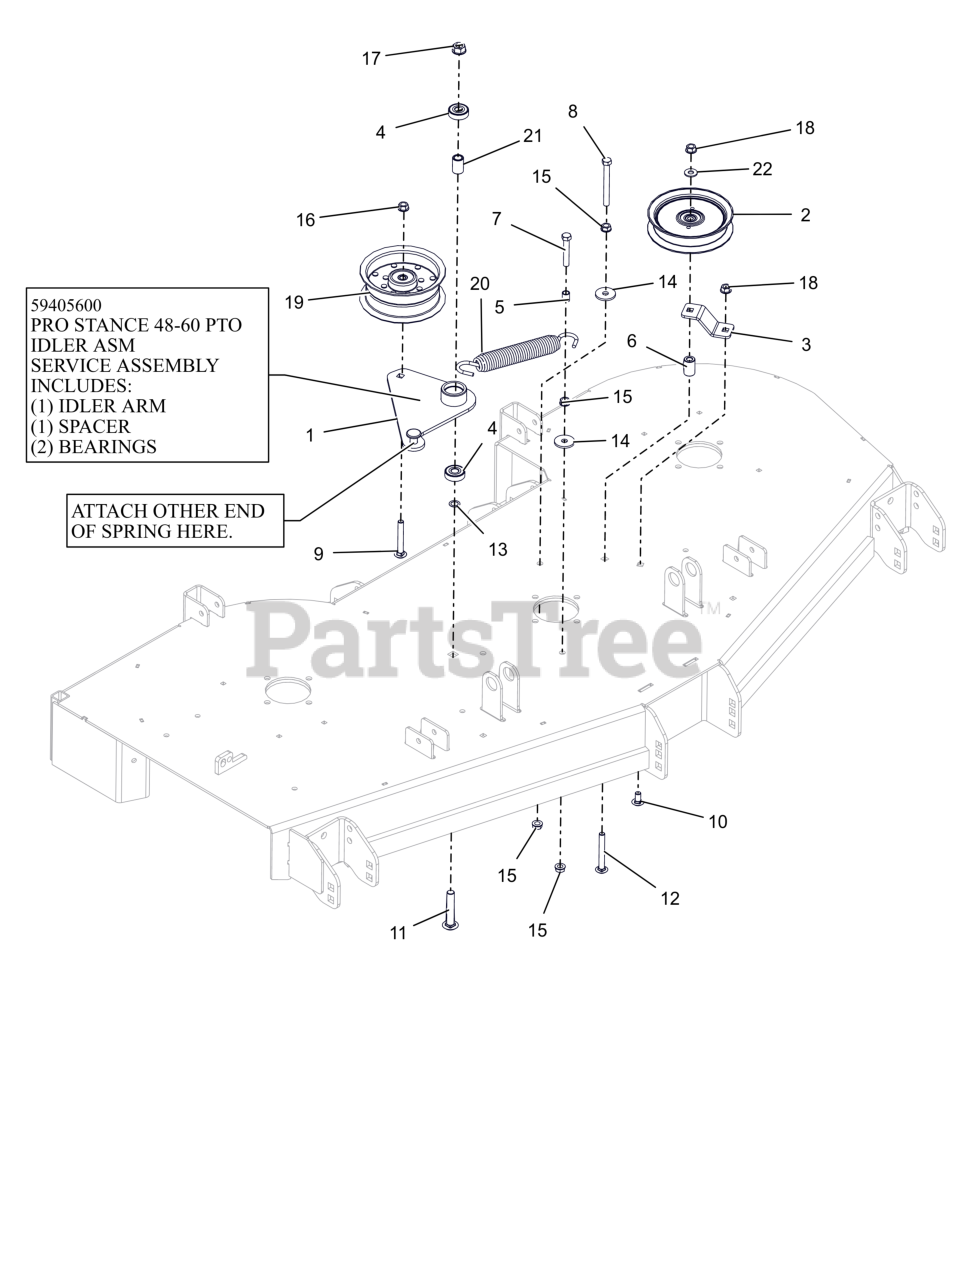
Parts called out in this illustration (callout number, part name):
1	WLDMT, PTO IDLER ARM
1	PTO IDLER ASSEMBLY
2	IDLER, FLAT 5.00"
3	PTO FIXED IDLER MTG BRKT -RED
4	BRG-BALL .500X1.38X.437
5	SPCR, SLV .385X.500X.652
6	BUSHING, SLV .380X.750X1.190
7	BLT,HEX .38-16X2.25 G5 ZCC
8	BLT, HEX .38-16X3.50 G5 ZCC
9	BLT, RHSN .38-16X2.75 G5 ZCC
10	BTL,RHSSN .375-16 X 0.75 G5 FPB
11	BTL,RHSSN .500-13 X 2.75 G5 ZCC
12	BTL,RHSSN .375-16 X 3 G5 ZCC
13	WASHER, .500X.750X.020 THRUST
14	WSHR,FLT .406X1.375X.135 ZCC
15	NUT, SPNLK-FLG .38-16 G5 ZCC
16	NUT-LK-CTR-FLG .375-16 GF ZCC
17	NUT-LK-CTR-FLG .500-13 GG ZCC
18	NUT-LK-CTR-FLG .375-16 GF ZCC
19	PULLEY, FLAT 5.00X2.36X.375
20	SPRING, EXTENSION
21	SPACER .510 X .75 X 1.1485
22	WSHR,FLT .375X.875X.083 ZCC
